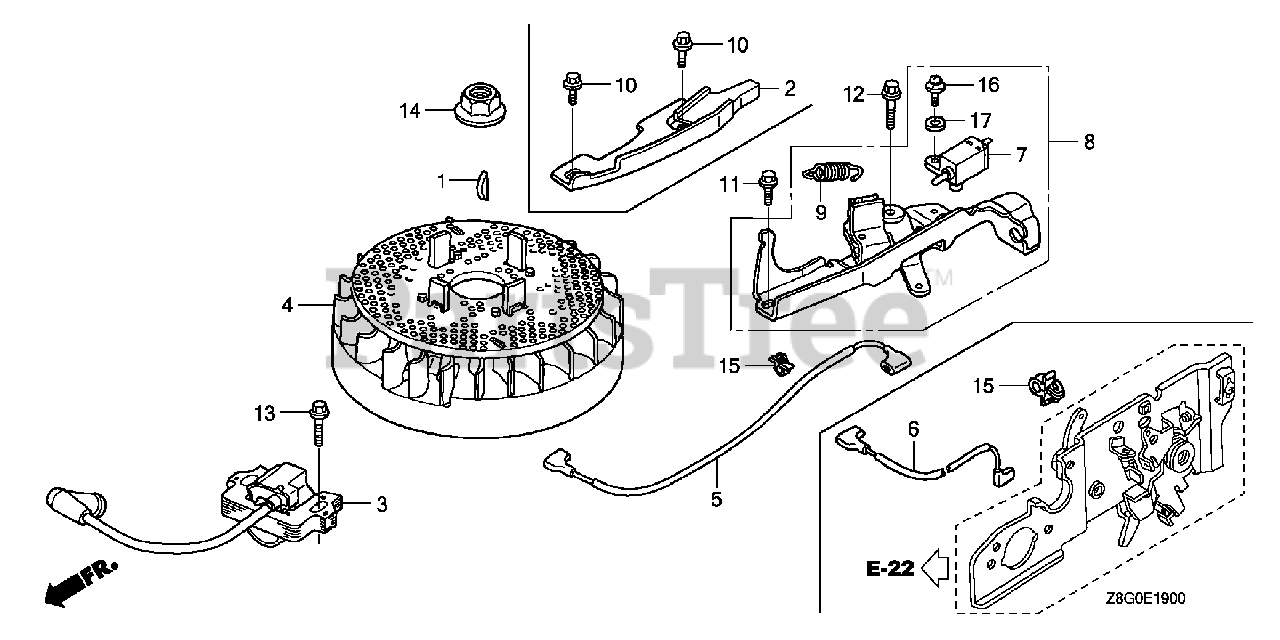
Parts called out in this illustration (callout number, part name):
1	KEY, SPECIAL WOODRUFF (25X18)
3	COIL ASSY., IGNITION (USE FOR F/W OF TEC) (TEC)
4	FLYWHEEL ASSY. (TEC) (USE FOR IGN. COIL OF TEC)
5	WIRE, STOP SWITCH
7	SWITCH ASSY., ENGINE STOP (N.C)
8	BRAKE ASSY.
9	SPRING, BRAKE LEVER
11	BOLT, FLANGE (6X14) (CT200)
12	BOLT, FLANGE (6X23) (CT200)
13	BOLT, FLANGE (6X20) (CT200)
14	NUT, SPECIAL (14MM)
15	CLIP A, CABLE (3.8MM BLACK) (NIFCO)
16	SCREW-WASHER (4X12)
17	WASHER, PLAIN (4MM)
